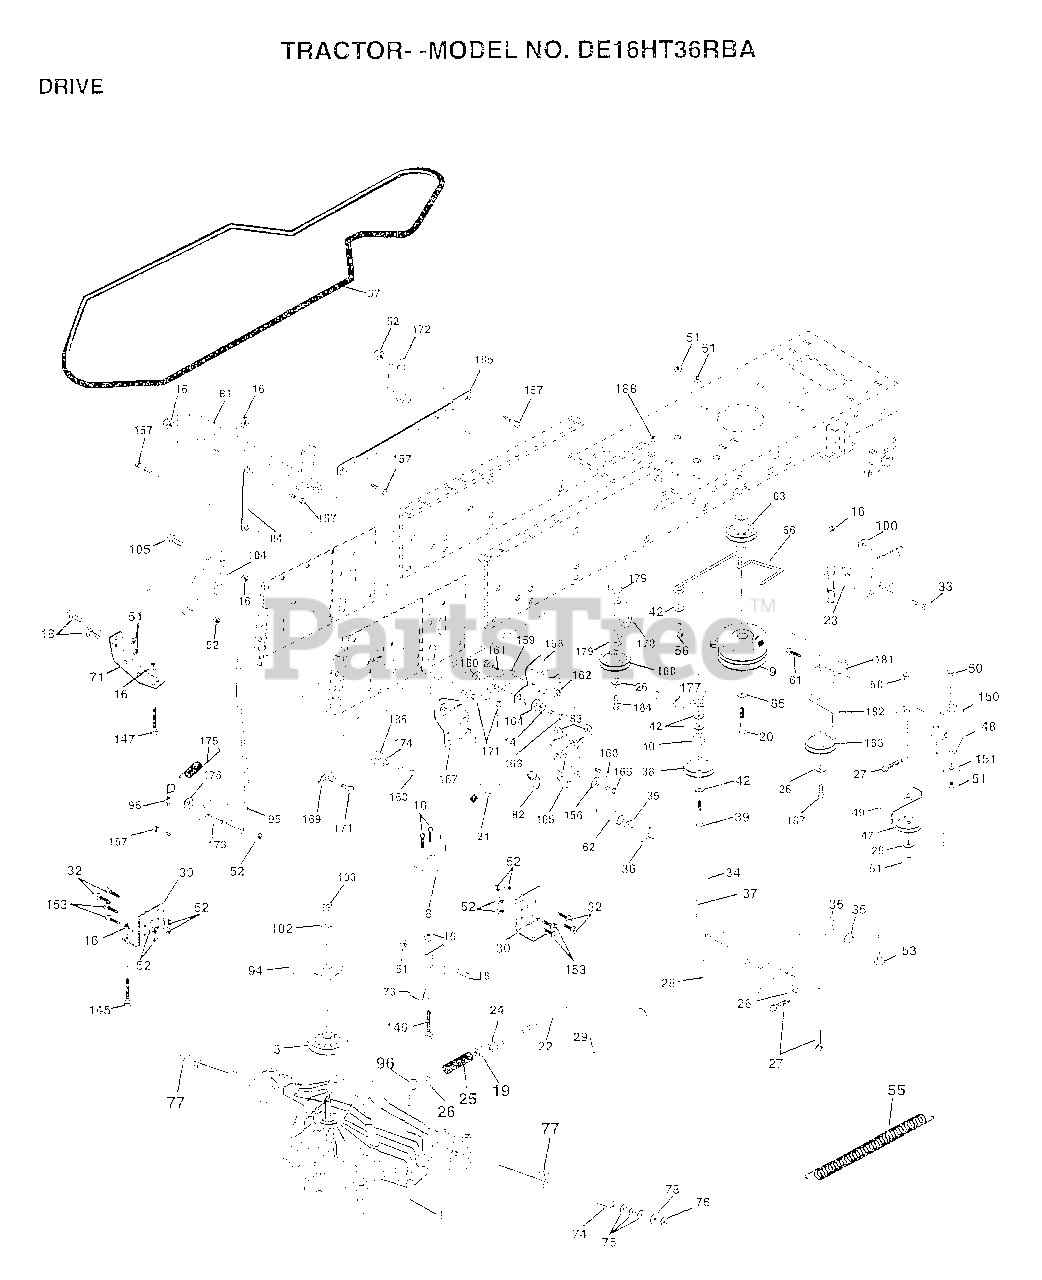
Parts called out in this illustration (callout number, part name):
3	PULLEY.TRANSAXLE
8	ROD.SHIFT.FENDER.ADJ.LT.CRD
9	CLUTCH.ELEC.EVX
10	PIN COTTER 1/8
14	LOCKWASHER
16	NUT
18	BOLT
19	NUT
20	BOLT.7/16-20X4.25
21	KNOB DLX BLK/BLK
22	ROD.BRAKE.CRD
23	BRACKET.CLUT.MTG.
24	NUT
25	SPRING ROD LT
26	WASHER
27	COTTER PIN
28	ROD.BRAKE.PARK.LT
29	PLUNGER CAP T
30	TRANSAXLE MTG BKT
32	BOLT
34	SHAFT.ASM.PEDAL.FOOT.CRD
35	NYLON BEARING
36	WASHER LT
38	PULLEY.FLAT.IDLER
39	BOLT
40	SPACER T
42	WASHER
48	BELLCRANK.CLUTCH
49	RETAIN BELT
53	"LINK, CLUTCH T"
55	"SPRING, RETURN LT"
57	"V-BELT.KEV.112"""
61	SCREW
62	PEDAL COVER T
63	PULLEY.CLUTCH.EVX
65	LOCKWASHER
66	KEEPER-BELT
71	STRAP TORQ LH HYD
73	"STRAP-TORQUE,RH"
74	SPACER SPLIT
75	WASHER
76	E-RING LT
77	SQUARE KEY
78	WASHER
81	ASM.SHAFT
82	"SPRING,TORSION"
83	WASHER
84	LINK.TRANSAXLE
94	"FAN 7"" HYDRO"
95	CNTRL.ASM.BYPASS.HYDRO
96	RETAINER M
100	WASHER M
102	WASHER BELLEVILLE
104	ARM CONTROL HYDRO
105	SCREW CAP 5/16-18
145	BOLT.HEX.FLGHD
146	BOLT.HEX.FLGHD.
147	BOLT.HEX.FLGHD
150	BUSHING.BELLCRANK.GRD.DR
151	WASHER
156	WASHER.SRRTD.5/16
157	"BOLT,SHOULDER"
158	BRKT.SHIFT.MOUNT
159	HUB.SHIFT
160	WASHER
161	BOLT T
164	WASHER.5/8X.281X10GA
165	BRKT.PIVOT.LEVER
166	SCREW.5/16-18X5/8
167	BRKT.SUPT.SHIFT.CRD
168	BOLT.SHOULDER.5/16-18X.561
169	PLATE.FASTENING
171	SCREW LT
172	LINK.SHAFT.CRD.HYDRO
173	BKRT.HYDRO.BYPASS.CRD
175	SPRING.BYPASS.CRD
176	WASHER
177	KEEPOER.FLAT.IDLER
178	KEEPER.BELT.IDLER
179	WASHER
180	PULLEY.FLAT
181	BRKT.IDLER.GRD.DR.CRD
182	"KEEPER.BELT.2.5"".OD.CRD"
183	PULLEY.V-IDLER
184	SCREW.HXWSH.3/8
185	SHAFT.ASM.SHIFTER.FRT.CRD
186	HUB.TAPERED.ROUND.CRD
187	SCREW
